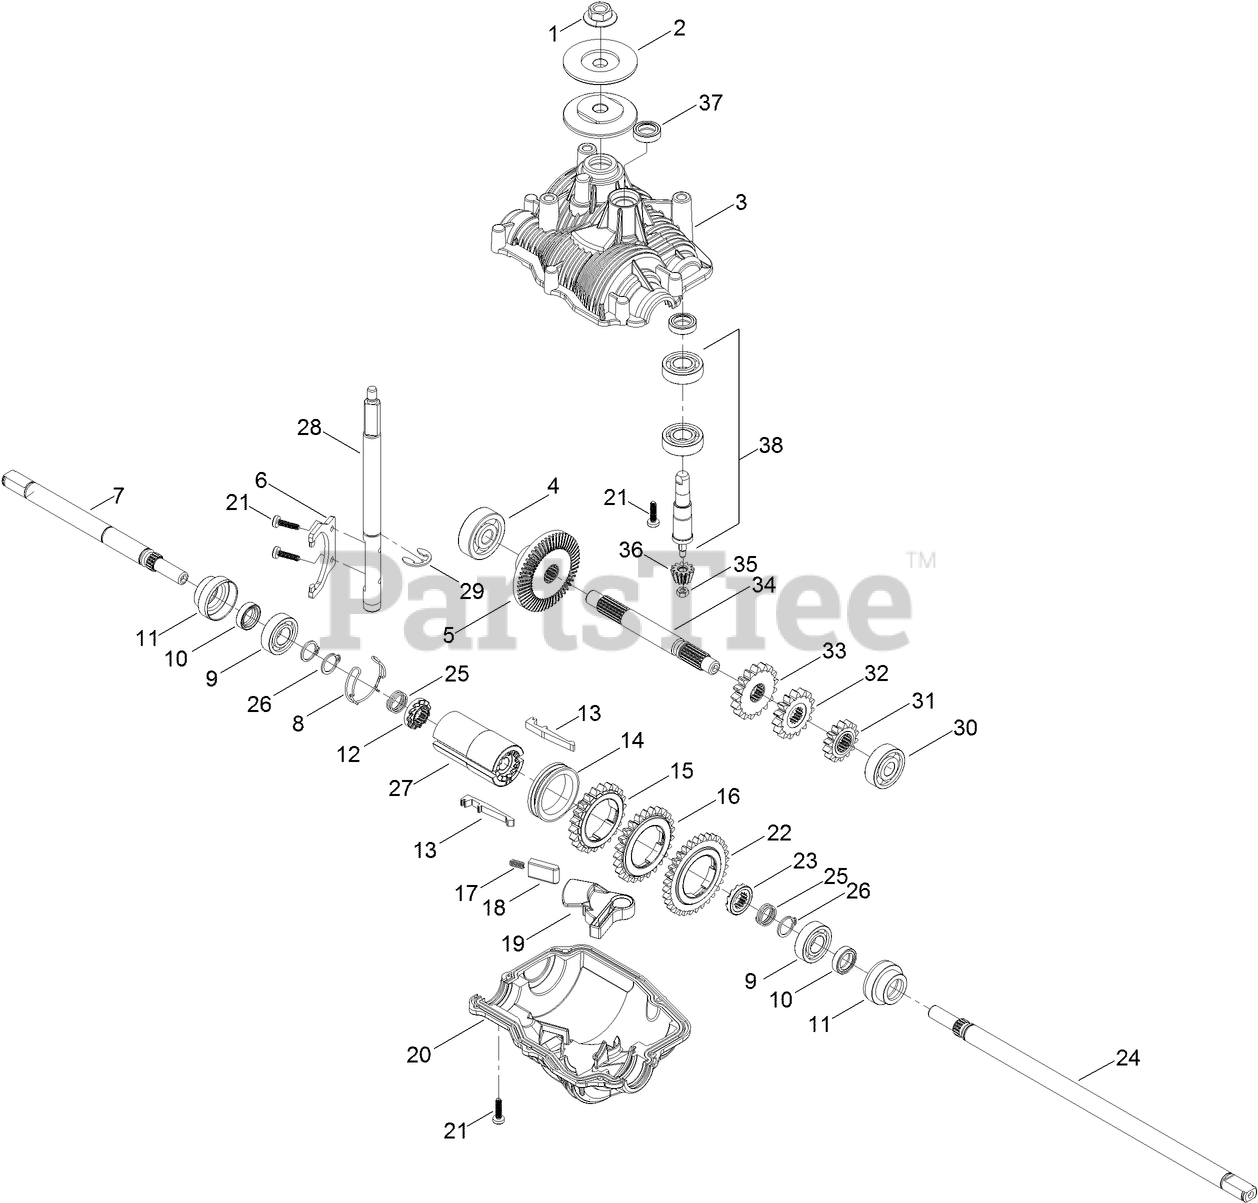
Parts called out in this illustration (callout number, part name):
1	NUT-FLANGE
2	FLANGE-PULLEY
3	CASE-UPPER, TRANSMISSION
4	BEARING-BALL
5	GEAR-BEVEL, 53 TOOTH
6	FORK-SHIFT
7	SHAFT-OUTPUT, SHORT
8	SPRING-RETAINING
9	BEARING-BALL
11	BUSHING-SHAFT, OUTPUT
12	CLUTCH-DOG
13	KEY-SHIFT
14	RING-SHIFT
15	GEAR-OUTPUT, 22 TOOTH
16	GEAR-OUTPUT, 25 TOOTH
17	SPRING-INDEXING, SHIFTER
18	PIN-INDEXING, SHIFTER
19	LEVER-INDEXING, SHIFTER
20	CASE-LOWER, TRANSMISSION
22	GEAR-OUTPUT, 32 TOOTH
23	CLUTCH-DOG, RH
24	SHAFT-OUTPUT, LONG
25	SPRING-COMPRESSION, CLUTCH
26	RING-RETAINING
27	HUB-GEAR, OUTPUT
28	SHAFT-SHIFT
29	RING-RETAINING
30	BEARING-BALL
31	GEAR-INTERMEDIATE, 14 TOOTH
32	GEAR-INTERMEDIATE, 15 TOOTH
33	GEAR-INTERMEDIATE, 17 TOOTH
34	SHAFT-INTERMEDIATE
35	NUT-SHAFT, INPUT
36	GEAR-BEVEL, 12 TOOTH
38	SHAFT-INPUT
